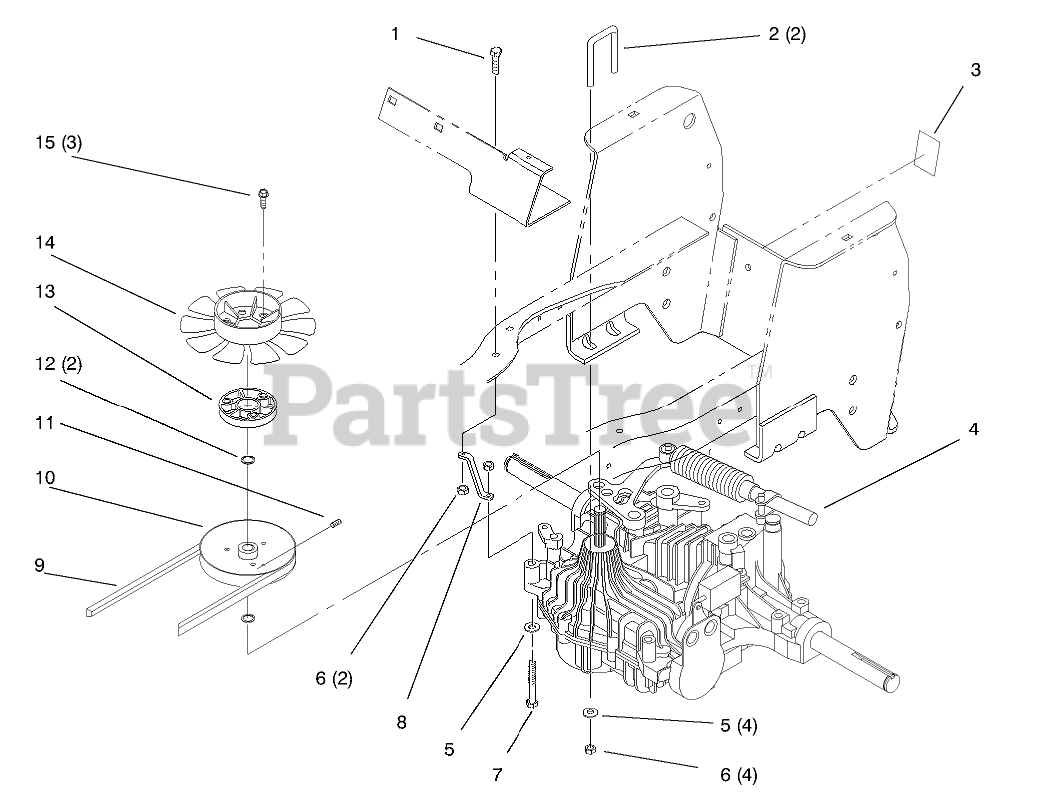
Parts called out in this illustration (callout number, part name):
1	SCREW-HH
2	U-BOLT
3	Decal-Hydro Valve (Only On: 72085)
3	Decal-Bypass (Only On: 72104)
4	TRANSAXLE - HYDROSTATIC
5	WASHER-PLAIN
6	NUT-LOCK, NI
7	SCREW-HH
8	STRAP-TRQ HY
9	V-BELT, HYDRO
10	PULLEY-HYDRO TRANS
11	SCREW-HSH
12	SNAP RING
13	SPACER - FAN
14	FAN - HYDRO
15	SCREW-HWHTF
